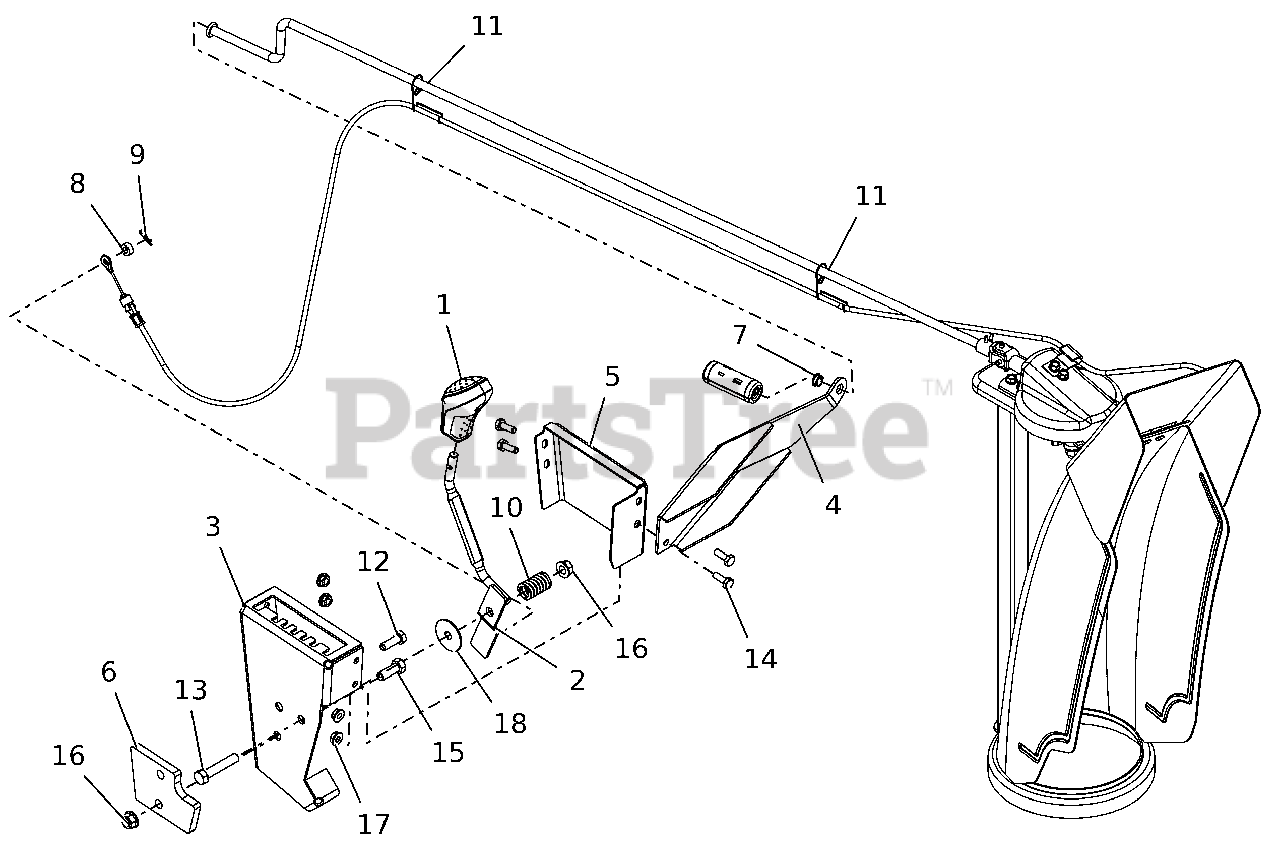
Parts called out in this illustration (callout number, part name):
1	KNOB, CONTROL, DASH
2	WLDMT, CONTROL LEVER (DEFL)
3	BRKT, DEFLECTOR LEVER
4	BRKT, CHUTE CRANK ROD HOLD
5	BRKT, DEFLECTOR COVER
6	BRKT, DEFLECTOR SPACER
7	BUSHING, POLYLINER-.38 SNAPIN
8	BSHG-SLV .265X.500X.219
9	PIN-HAIR INT .06X.18X.77
10	SPRG, COMPRESSION
11	CLIP, CABLE RETAINER
12	BLT, HEX M8-1.25X25 G8.8 ZCC
13	BLT,HEX .38-16X2.00 G5 ZCC
14	BLT, HEX .25-20X.75 G5 ZCC
15	BLT, HEX .38-16X1.00 G5 CKF
16	NUT-LK-TOP-FLG .38-16 ZC120
17	NUT-LK-CTR-FLG .25-20 ZC120
18	WSHR,FLT .380X1.50X.062 ZCC
